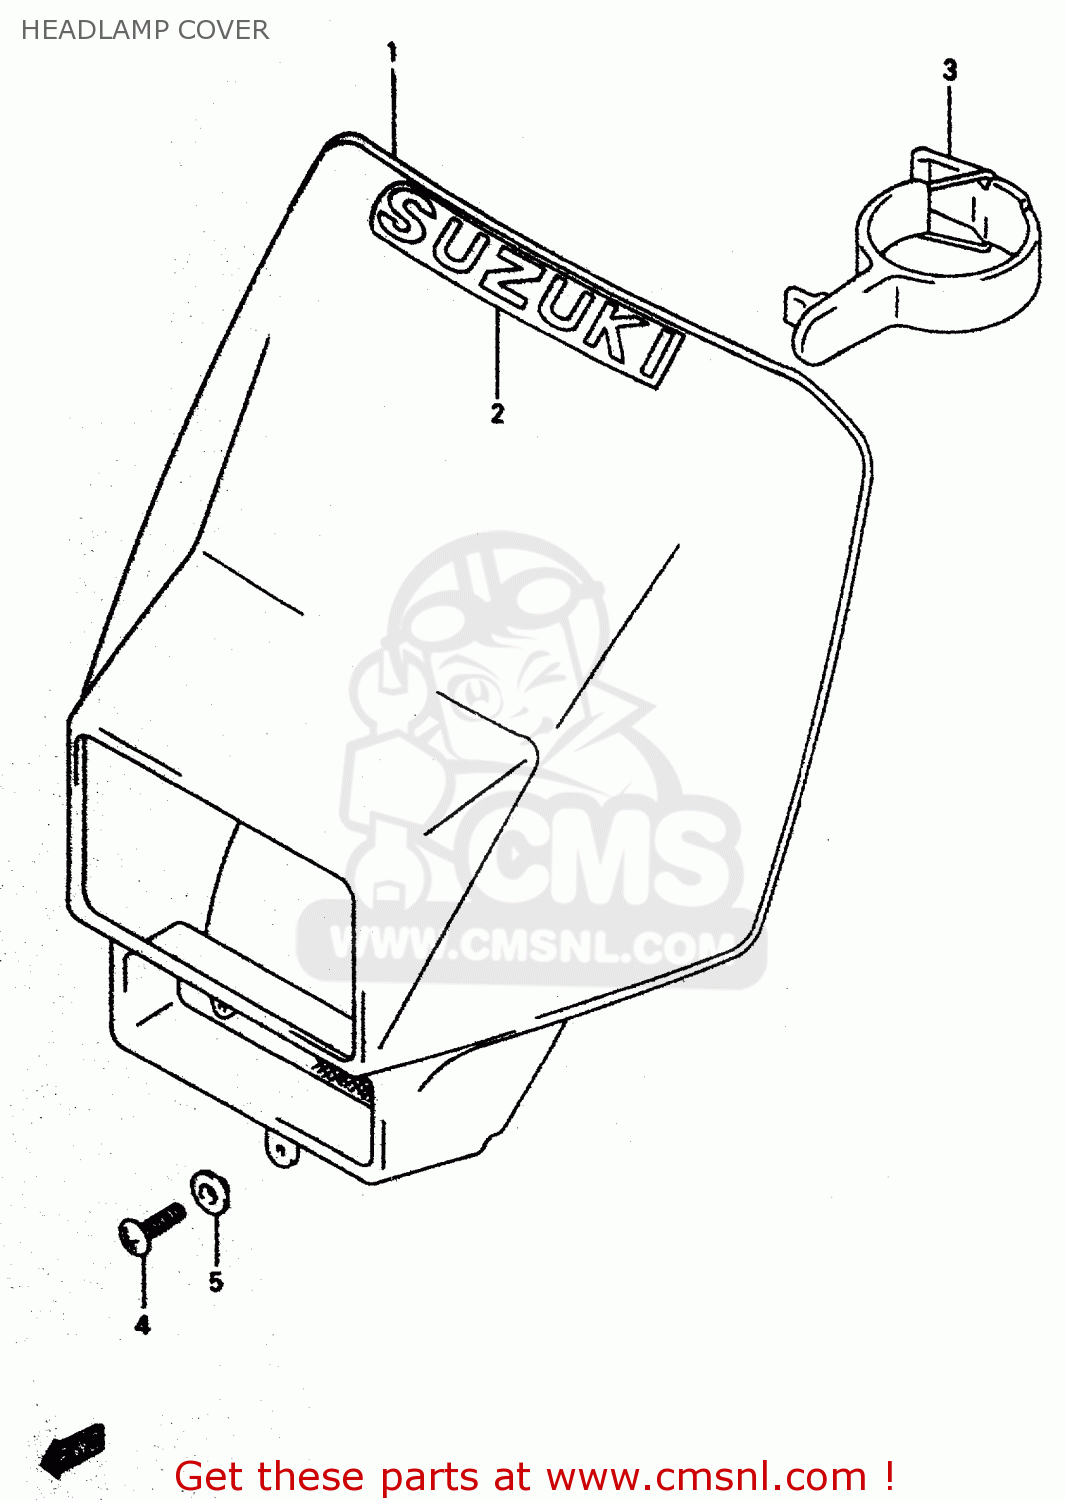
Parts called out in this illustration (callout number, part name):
1	COVER,HEADLAMP
2	EMBLEM,SUZUKI
3	BAND,HEADLAMP COVER
4	SCREW(5X12)
5	WASHER
